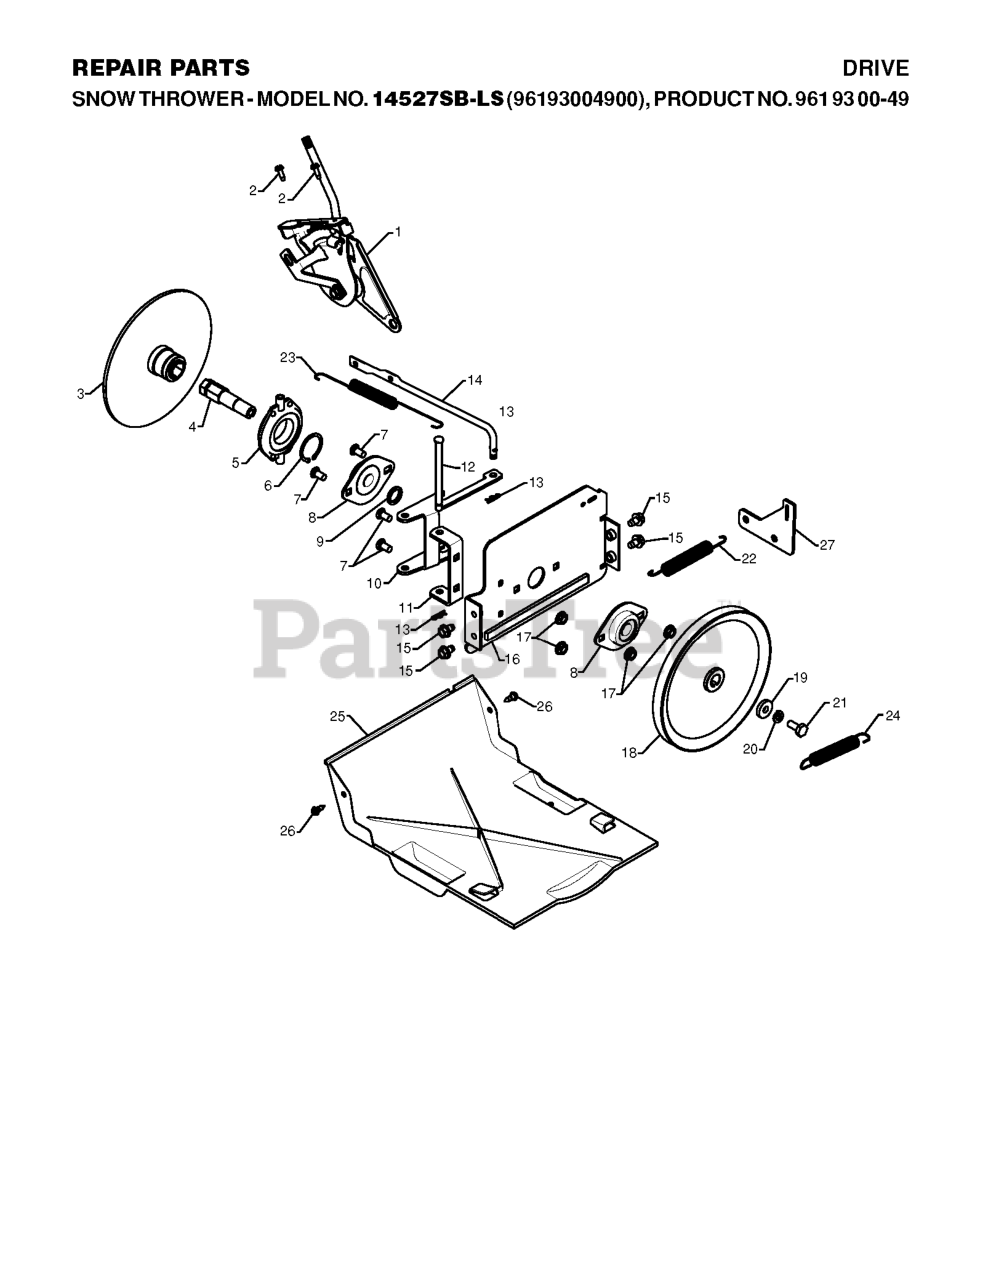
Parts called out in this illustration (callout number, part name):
1	HEAD ASSY SPEED
2	SCREW #10-24 X 5/8
3	DRIVE PLATE WELDMENT
4	SHAFT.HEX.SHORT
5	TRUNNION BEARING ASSY
6	RETAINING RING (2 2)(3 2)
7	BOLT
8	BEARING FLANGE
9	SPACER, BEARING
10	LEVER.SHIFTER.PLATE.BLACK
11	BRACKET, SHIFTER SUPPORT
12	PIN, PIVOT LEVER
13	RETAINER CLIP PM
14	ROD.CLUTCH.YELLOW.ZINC(VT)
15	Screw 5/16-18 x 1/2 Hex, Self Tapping 5/16-18 x 1/2
16	PLATE.DRIVE.MOUNTING.BLACK
17	NUT.FLANGE.5/16
18	PULLEY.TRACTION.7.75
19	WASHER, FLAT
20	WASHER.LOCK.HVY.HLCL.SPR.5/16
21	Screw, Hex Head 5/16-18 x 3/4
22	SPRING.TRACTION.IDLER
23	SPRING.RETURN
24	SPRING, BRAKE
25	PAN.BOTTOM.PLASTIC
26	SCREW, HEX HEAD, TAPPING
27	BRACKET.TRACTION.SPRING.
